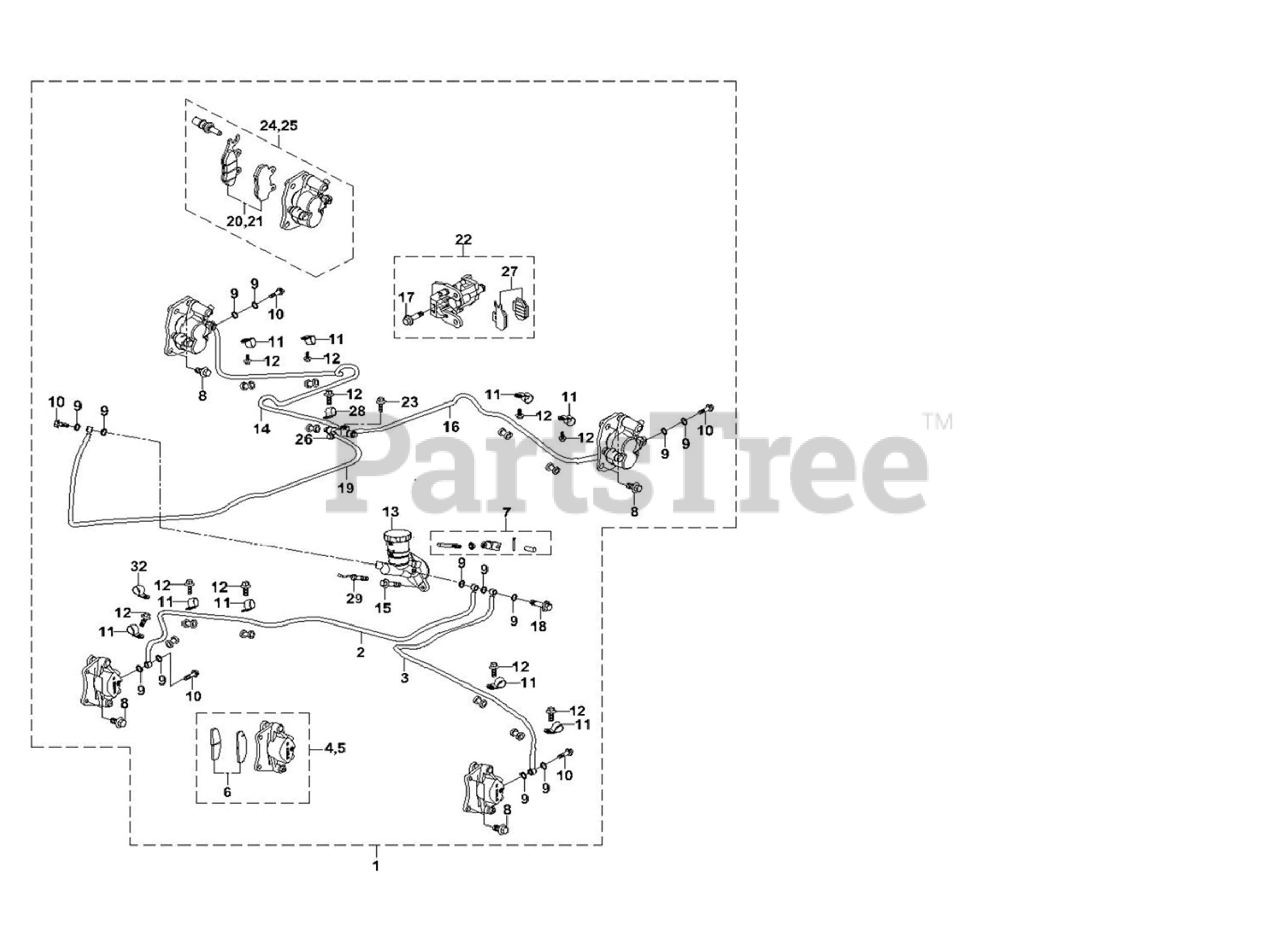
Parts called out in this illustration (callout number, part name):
1	BRAKE SYSTEM ASSEMBLY
2	BRAKE LINE - FRONT RIGHT
3	BRAKE LINE - FRONT LEFT
4	DISC BRAKE CALIPER ASSEMBLY - FRONT RIGHT
5	DISC BRAKE CALIPER ASSEMBLY - FRONT LEFT
7	BRAKE ROD ASSEMBLY
8	Hexagon Flange bolt M10x1.25x22
9	hydraulic oil pipe washer
10	hydraulic oil pipe Bolt I
11	Oil pipe attach clamp I
12	Hexagon Flange Bolt M6x16
13	MAIN BRAKE PUMP ASSEMBLY
14	BRAKE LINE- REAR RIGHT
15	Hexagon Flange Bolt M10x1.25x25
16	BRAKE LINE - REAR LEFT
17	Hexagon Flange BoltM10x1.25x55
18	BANJO BOLT II
19	BRAKE LINE - MIDDLE
20	DISC BRAKE PAD - FRONT LEFT
21	DISC BRAKE PAD - FRONT RIGHT
22	PARKING BRAKE ASSEMBLY
23	Hexagon Flange BoltM6x25
24	DISC BRAKE CALIPER ASSEMBLY - REAR RIGHT
25	DISC BRAKE CALIPER ASSEMBLY - REAR LEFT
27	PARKING BRAKE PAD SET
28	Water Pipe Clip V
29	TAIL LIGHT BRAKE SWITCH
